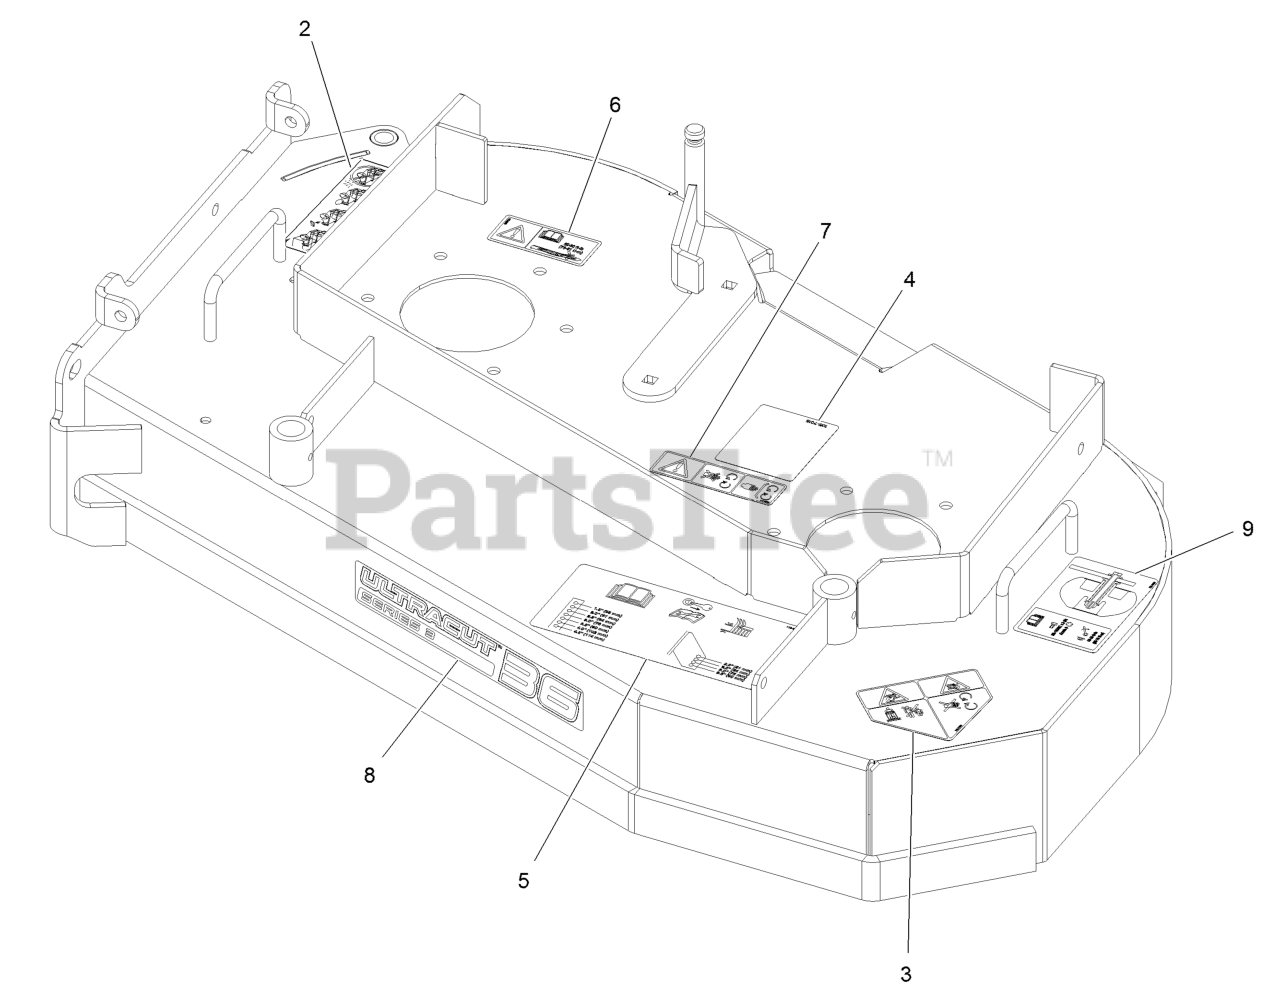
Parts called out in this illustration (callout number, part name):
2	DECAL-WARNING, BAGGER
3	DECAL-DANGER
4	DECAL-ROUTING, BELT
5	DECAL-ANTI-SCALP
6	DECAL-BOLT TORQUE
7	DECAL-COVER, MISSING
8	DECAL-ULTRACUT 36 SERIES
9	DECAL-ROLLER MOUNTING
